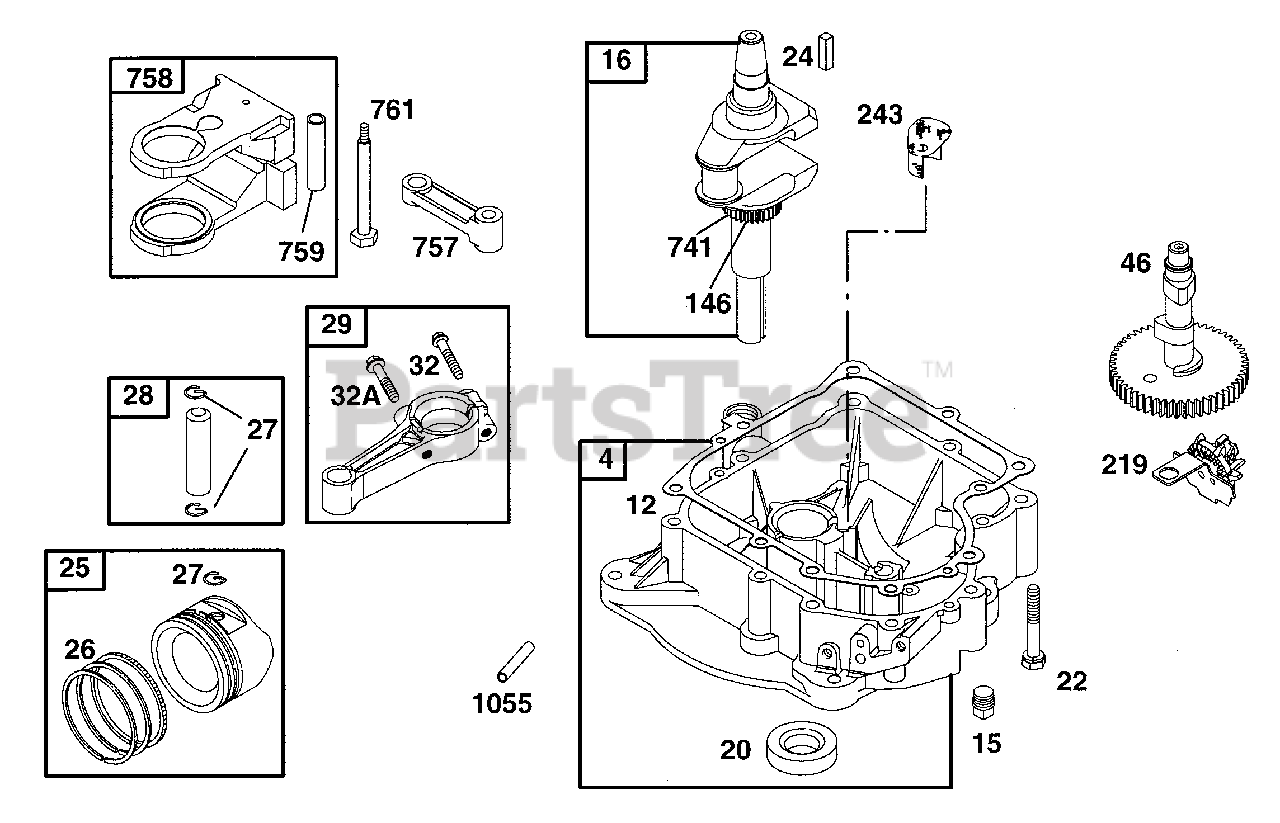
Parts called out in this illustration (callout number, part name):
4	Engine Sump
12	Crankcase Gasket (Standard)
15	Oil Drain Plug
16	Crankshaft
20	Oil Seal
24	Flywheel Key
25	Piston Assembly (Standard)
26	Ring Set (Standard)
27	Piston Pin Lock
28	Piston Pin (Standard)
29	Connecting Rod (Standard)
32	Connecting Rod Screw (1-7/8")
32A	Connecting Rod Screw (1-5/8")
146	Timing Key
741	Timing Gear
757	Counterweight Link
758	Counterweight
759	Counterweight Pin
761	Hex Screw
1055	Oil Pump Tube
